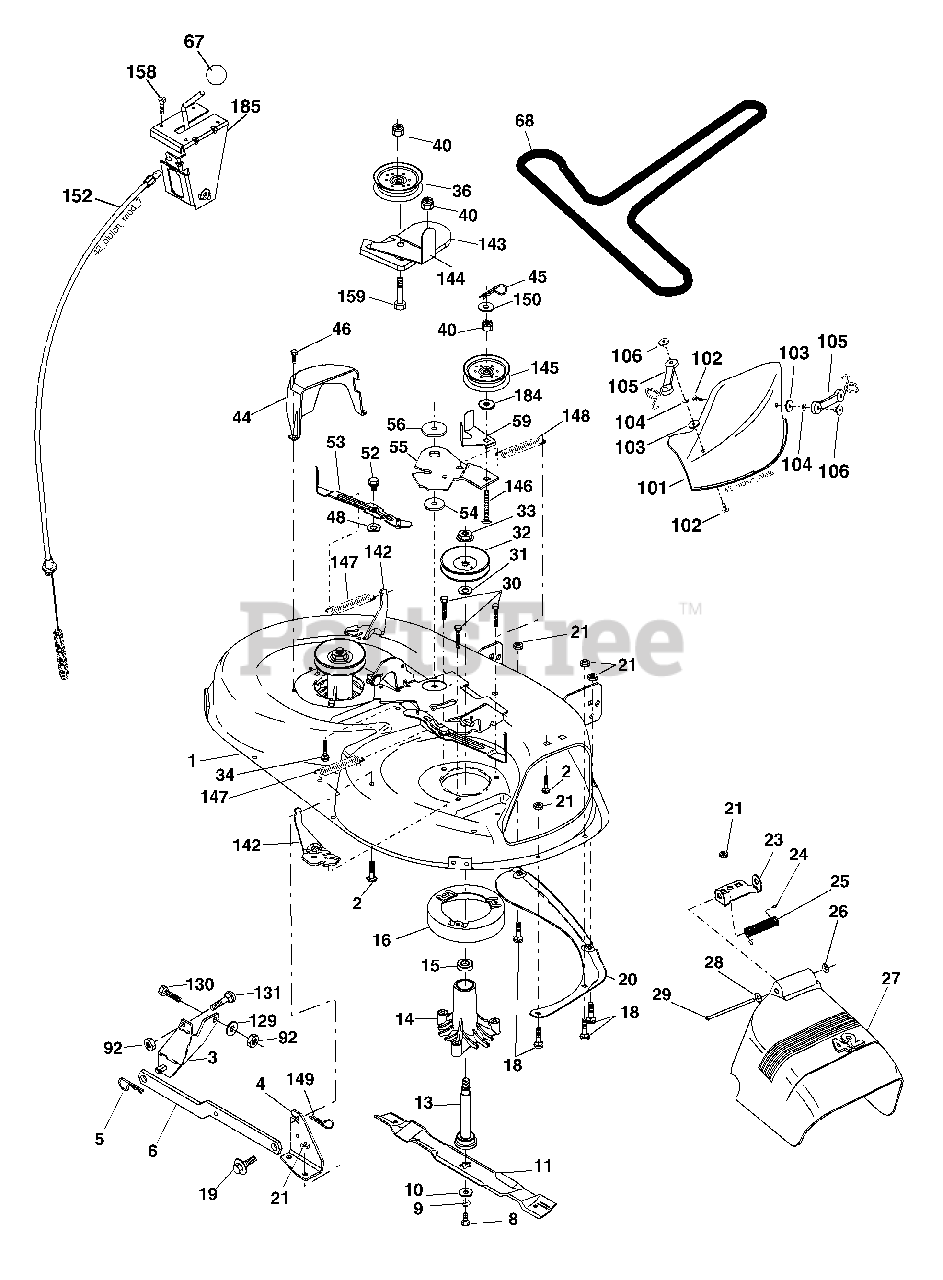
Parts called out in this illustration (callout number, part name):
1	Mower Deck Assembly, 42"
2	Bolt
3	Bracket Assembly,Sway Bar, Front
4	Bracket Sway Bar 38/42" Deck
5	Retainer Spring
6	Bar Sway Deck
8	Bolt, Hex 3/8-24 x 1.25 Gr. 8
9	Washer, Lock
10	Washer, Hardened
11	Blade, 42" Mulching Std
11	Blade, 42" Mulching Premium
11	Blade, 42" Hi-Lift
13	Shaft Assembly, Mandrel, Vented
14	Housing, Mandrel, Vented
15	Bearing, Ball, Mandrel
16	Stripper, Vented Mower Deck
18	Bolt, Carriage 5/16-18 x 5/8
19	Bolt, Shoulder
20	Baffle, Vortex
21	Nut Crownlock 5/16-18 Unc
23	Bracket, Deflector
24	Cap, Sleeve
25	Spring, Torsion, Deflector
26	Nut, Push
27	Shield, Deflector
28	Washer 11/32 x 5/8 x 16 Ga.
29	Rod, Hinge
30	Screw Thdrol Washer Head
31	Washer, Spacer
32	Pulley, Mandrel
33	Nut, Toplock, Flanged
34	Bolt Carr. Sh 3/8-16 x 1-1/2 Gr. 5
36	Pulley, Idler, Flat
40	Nut Crownlock 3/8-16 Unc
44	Guard, Mandrel, L.H.
45	Retainer
46	Screw, Thd. Roll 1/4-20 x 5/8
48	Washer, Hardened
52	Bolt, Shoulder 5/16-18 Unc
53	Arm Assembly, Pad, Brake
54	Washer, Hardened
55	Arm, Idler
56	Spacer, Retainer
59	Guard, TUV Idler
67	Knob
68	V-Belt
92	Nut
101	Mulcher Cover
102	Screw
103	Washer #10
104	Washer, Lock
105	Latch Assembly, Bagger
106	Nut, Weld
129	Washer 13/32 x 13/16 x 12 Ga.
130	Bolt, Fin Hex 3/8-16 Unc x 1 Gr. 5
131	Bolt, Rdhd Sqnk 3/8-16 Unc x1
142	Arm Spring Brake Mower
143	Bracket Arm Idler 42"
144	Keeper Belt 42" Clutch Cable
145	Pulley Idler Flat
146	Bolt Carriage Idler
147	Spring Extension
148	Spring Return Idler
149	Retainer Spring Yellow Zinc
150	Washer 9/32 x 3/4 x 10 Ga.
152	Cable Clutch 42 In
158	Screw Hex Thd Cut 1/4-20 x 1/2
159	Bolt Rdhd Sqn 3/8-16 Unc x 3/4
184	Washer 13/32 x 7/8 x 10 Ga.
185	Head Asm. Cable Clutch
